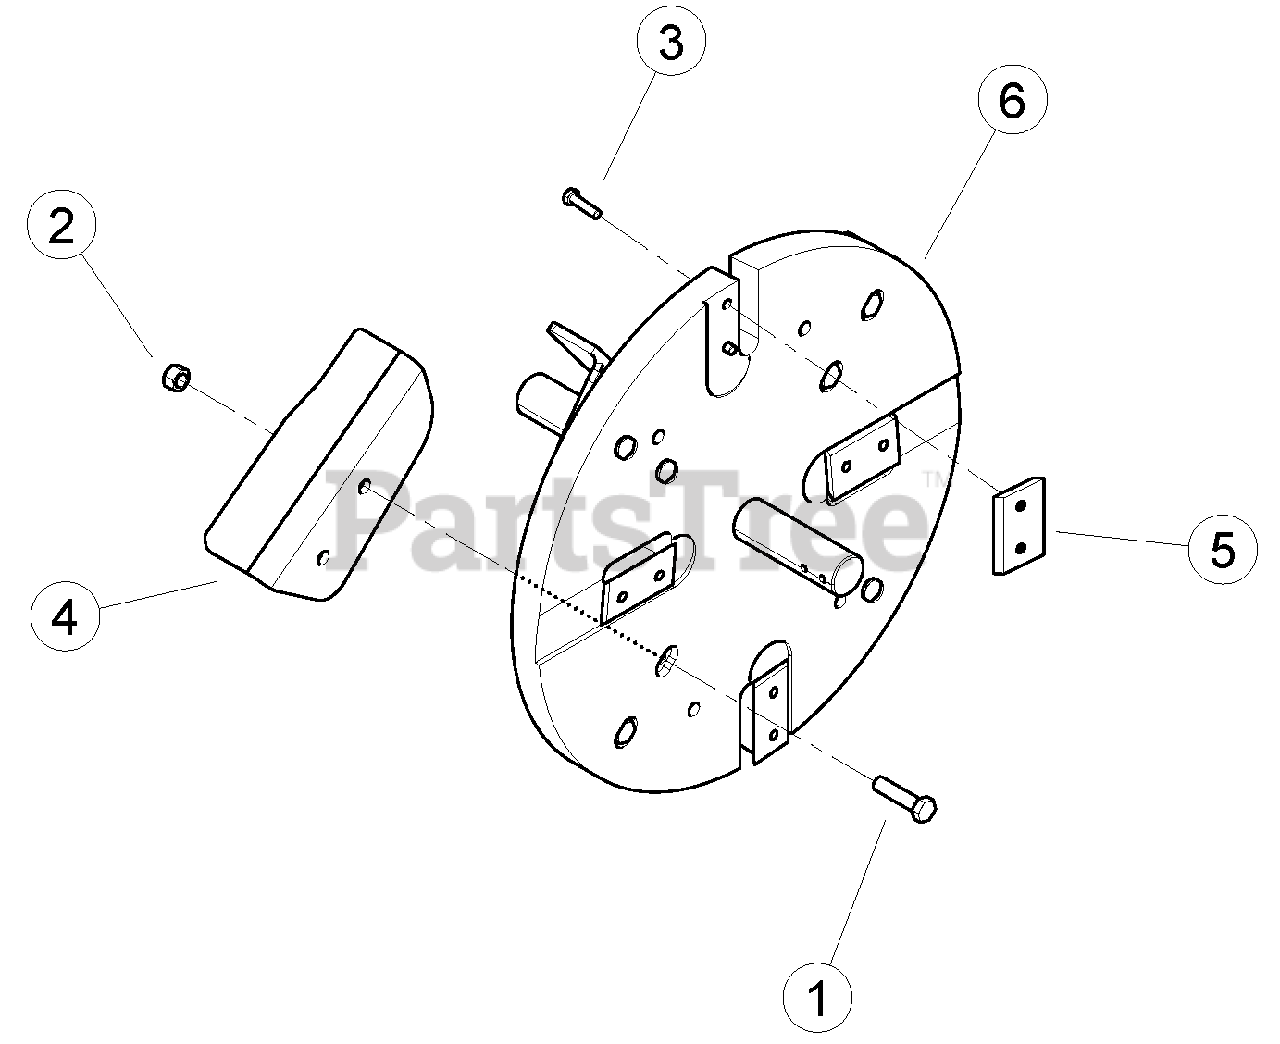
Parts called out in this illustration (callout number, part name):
1	BOLT, 1/2 X 2 GR5 HEX CAPSCREW ZP
2	NUT, 1/2" CENTERLOCK GRB ZP
3	BOLT, 5/16 X 1-1/4 HEX HD GR8 PATCH
4	PADDLE, 5" CHIPPER
5	KIT, CHIPPER BLADE
6	WELDMENT, 5" CHIPPER ROTOR
